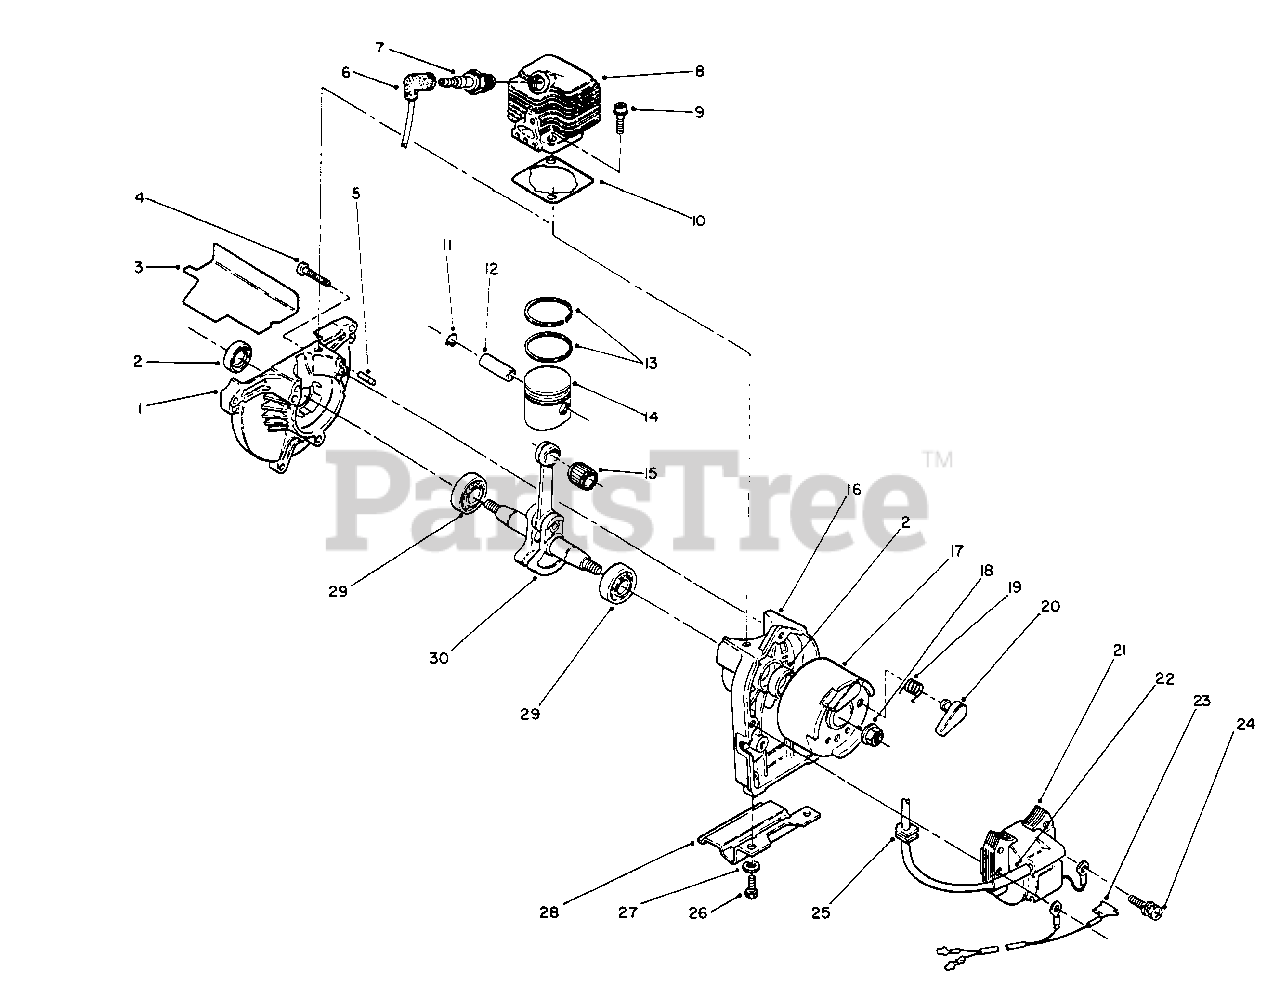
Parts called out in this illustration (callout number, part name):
1	Case-Drive
2	Seal-Oil
3	Gasket-Insulator
4	Screw-Pan Hd.
5	Pin-Dowel
6	Boot-Plug
7	Plug-Spark
8	Cylinder Head
9	Bolt-Cylinder Head
10	Gasket-Cylinder Head
11	Clip-Piston Pin
12	Pin-Piston
13	Set-Piston Ring
14	Piston Assembly (Incl. Ref. #12)
15	Bearing-Needle
16	Case-Starter
17	Flywheel Assembly (Incl. Ref. #19 & 20)
18	Nut-Conical
19	Spring-Return
21	Coil-Ignition
23	Wire Assembly
24	Bolt/Washer
27	Washer-Lock
29	Bearing-Main
30	Crankshaft Assembly
